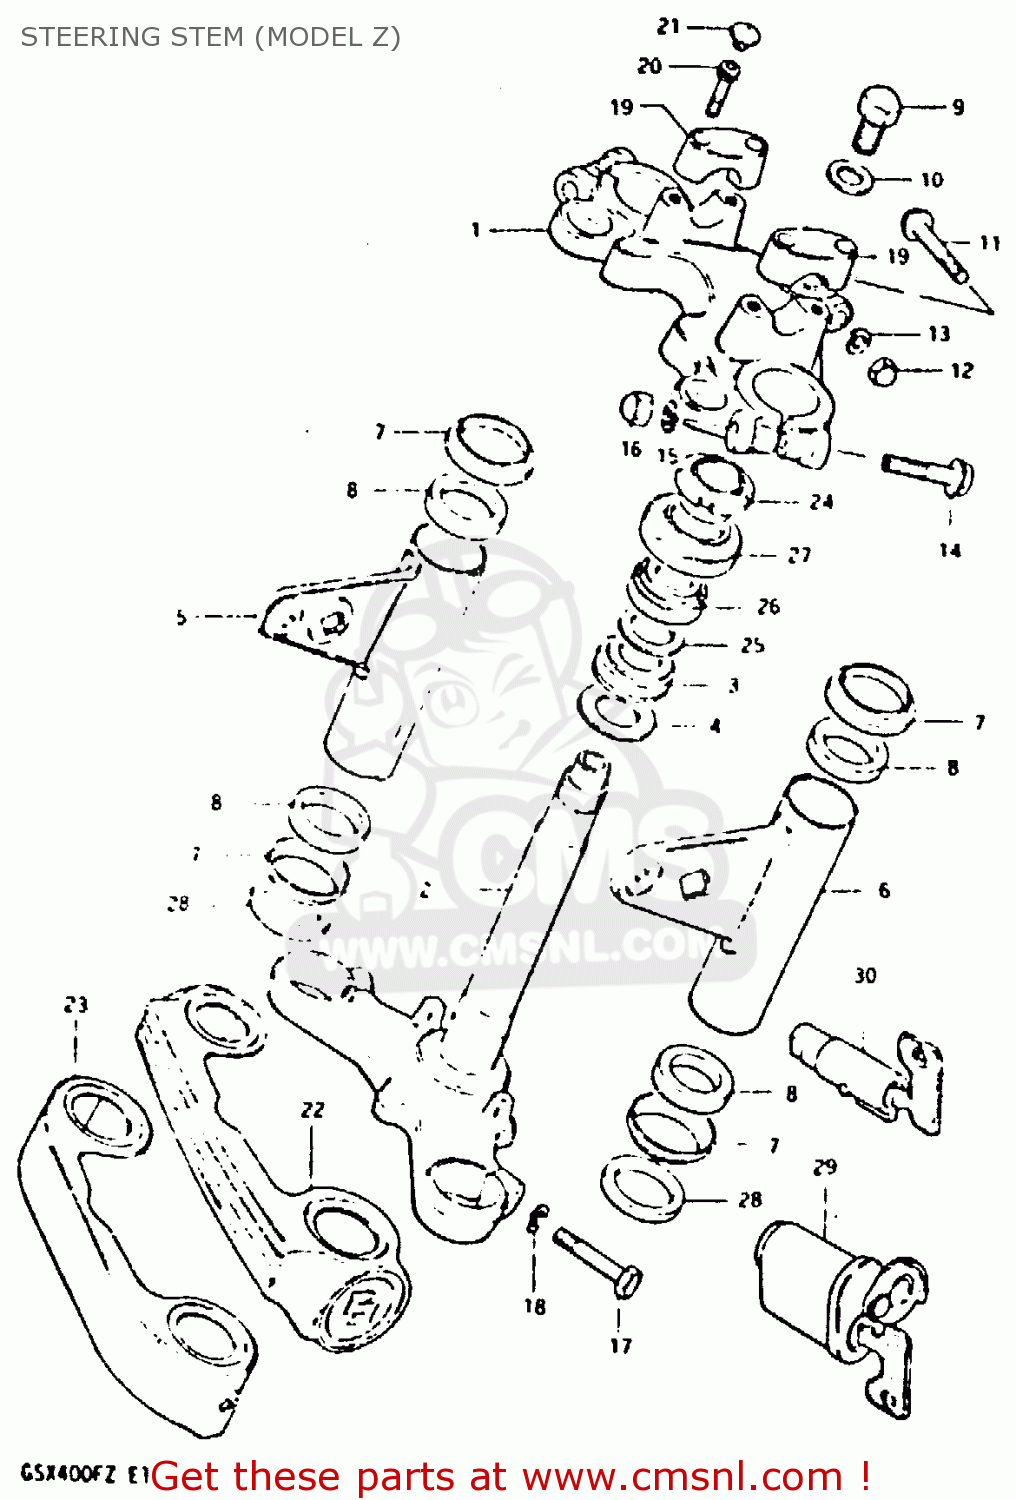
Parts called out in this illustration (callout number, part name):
1	HEAD,STEERING STEM
2	STEM,STEERING
3	BEARING
4	WASHER,THRUST
5	BRACKET,HEADLAMP,RIGHT
6	BRACKET,HEADLAMP,LEFT
7	CAP,HEADLAMP BRACKET
8	CUSHION,HEADLAMP BRACKET
9	BOLT 12X20
10	WASHER (12.5X26X1.6)
11	BOLT
12	NUT,M8X1.25X12
13	LOCK WASHER
14	BOLT 10X55
15	LOCK WASHER
16	NUT
17	BOLT 10X40
18	LOCK WASHER
19	HOLDER,HANDLEBAR(BLACK)
20	BOLT
21	CAP(OD:14.5)
22	COVER, FRONT FORK
24	NUT,STEERING STEM
25	WASHER(18.5X24X1)
26	TAPER,ROLLER BEARING
27	DUST SEAL,STEERING UPR
